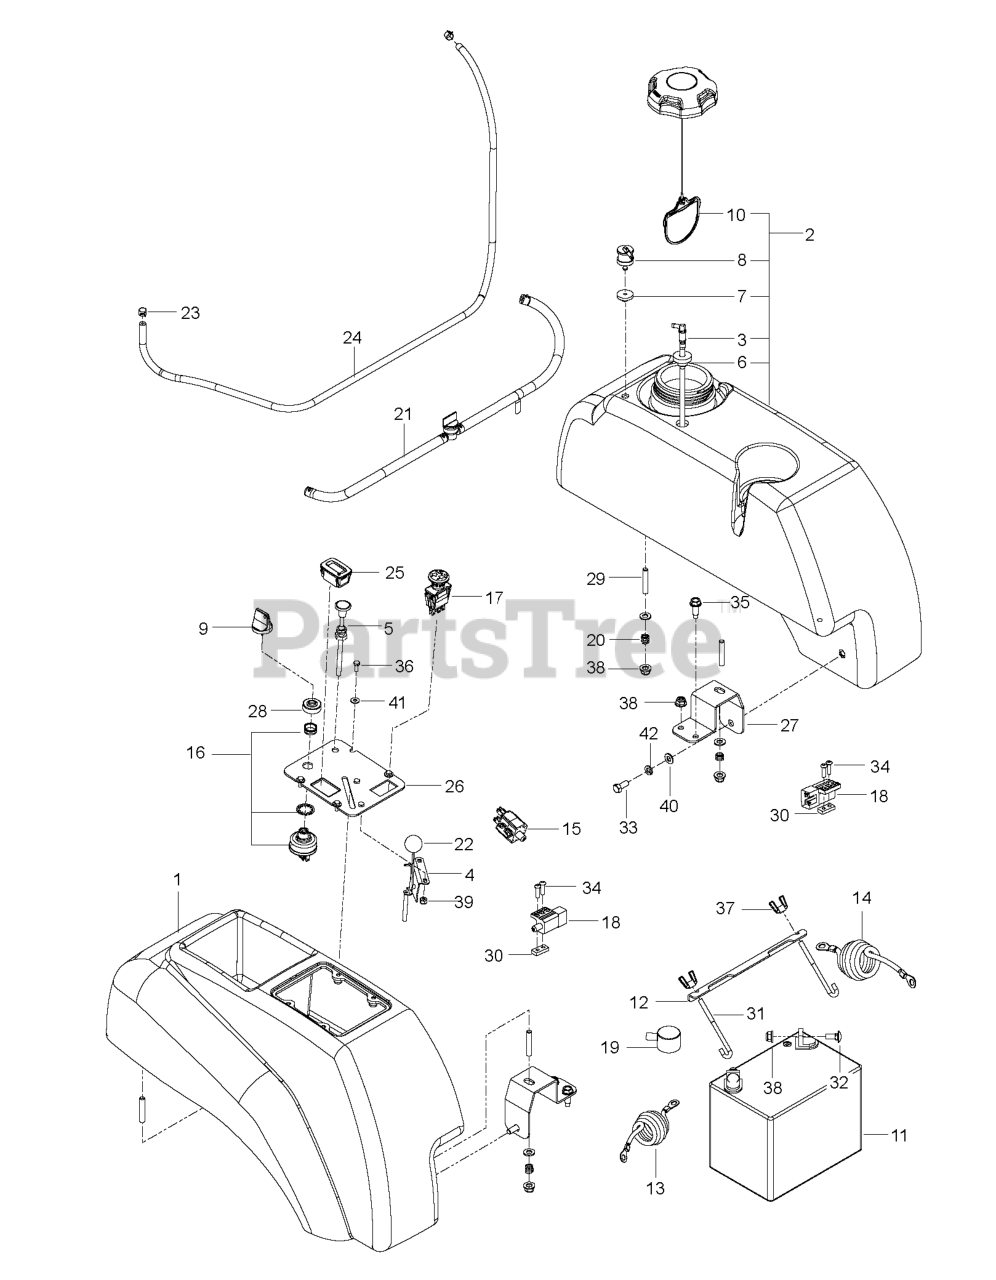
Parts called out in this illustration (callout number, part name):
1	FENDER CONSOLE
2	FUEL.TANK.ASSY.LH.MZ.GRY
3	FITTING, FUEL
4	THROTTLE CABLE
5	CHOKE CABLE
6	RUBBER GROMMET
7	GROMMET, CHECK VALVE
8	VALVE.FUEL.CHECK
9	KEY, IGNITION
10	CAP, FUEL
11	BATTERY, 12 V 330 AMP
12	BRACKET.BATTERY.MOUNT.PLATED
13	CABLE.BATT.SOLENOID.MZ.RED.25"
14	CABLE.GROUND.BATT.MZ.BLACK.39"
15	SWITCH, BRAKE 3P
16	SWITCH, IGNITION, INDAK
17	RP SWITCH.PTO.TERMINAL.STD.RED
18	SWITCH INTERLOCKT
19	COVER.TERMINAL.BATTERY
21	FUEL.HOSE.SHUT.OFF.ASM.10".10"
22	KNOB.ROUND.BALL.BLACK
23	CLAMP, HOSE
24	HOSE.3/16".VAPOR.LINE.27"LGTH
25	GUAGE.SRVCMNDR.HRMTR.
26	PLATE.CONSOLE.BLACK
27	SUPPORT, TANK, BLK
28	CAP IGNITION NUT
29	STUD, 5/16C
30	PLATE NUT ZTR
31	HOOK, "J"
32	RP BOLT 5/16-18 X3/4 ZN/YEL GR
33	BOLT.FIN.HEX.5/16-18X3/4
34	SCR #10-24 X .75 SKT HD BLK
35	HCS #10-24 X 1/2
36	SCREW
37	WING NUT 1/4
38	5/16-18 NYLOC FLANGE NUT
39	NUT 10-24 NYLOC
40	WASHER
42	WASH.5/16.SLW.ZD
